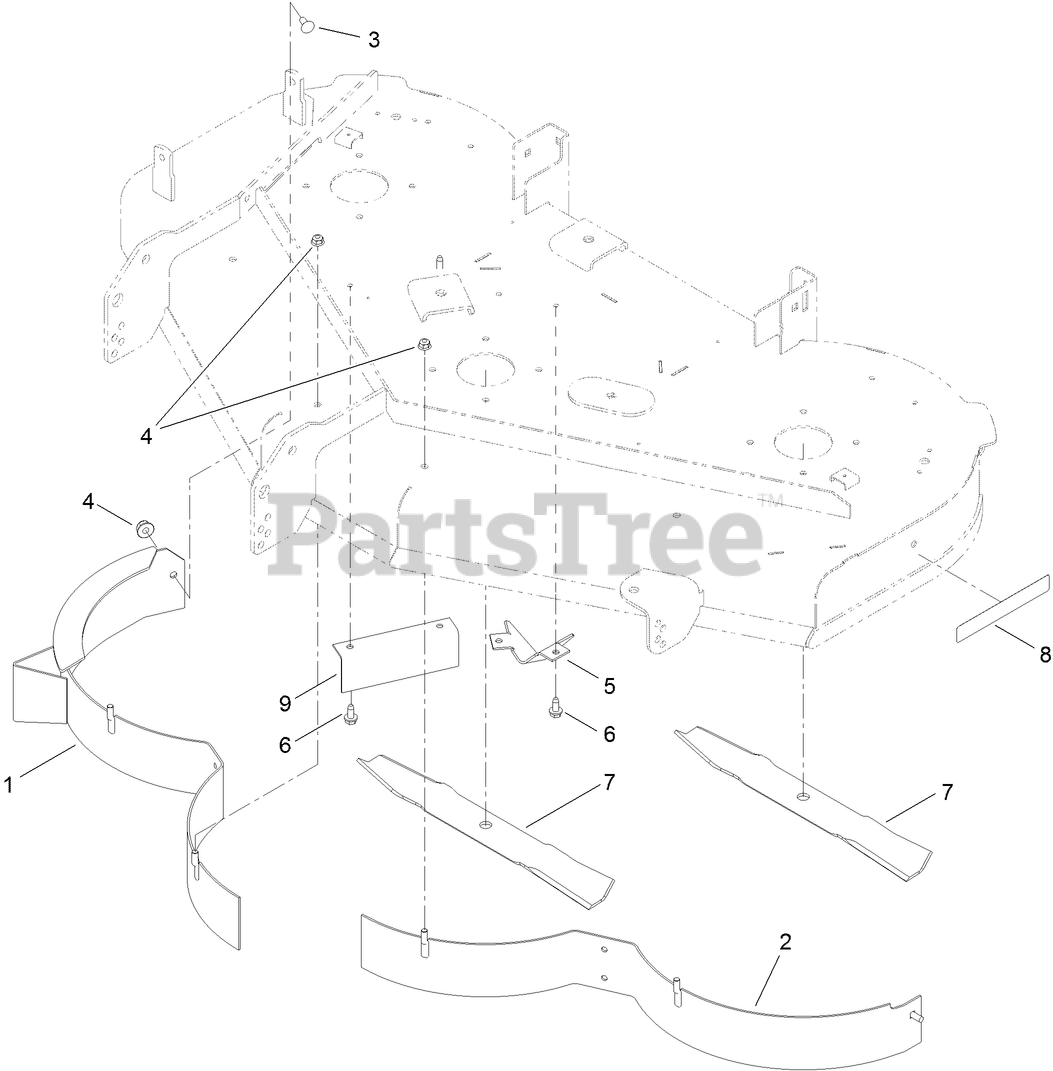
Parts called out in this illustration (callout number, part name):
1	BAFFLE-RH
2	BAFFLE-LH
3	BOLT-CARR
4	NUT-HF, NI
5	KICKER-FLANGED
6	SCREW-HWHTF
7	BLADE-MULCH, 17.50 INCH
8	DECAL-RECYCLER
9	BRACKET-RECYCLER
